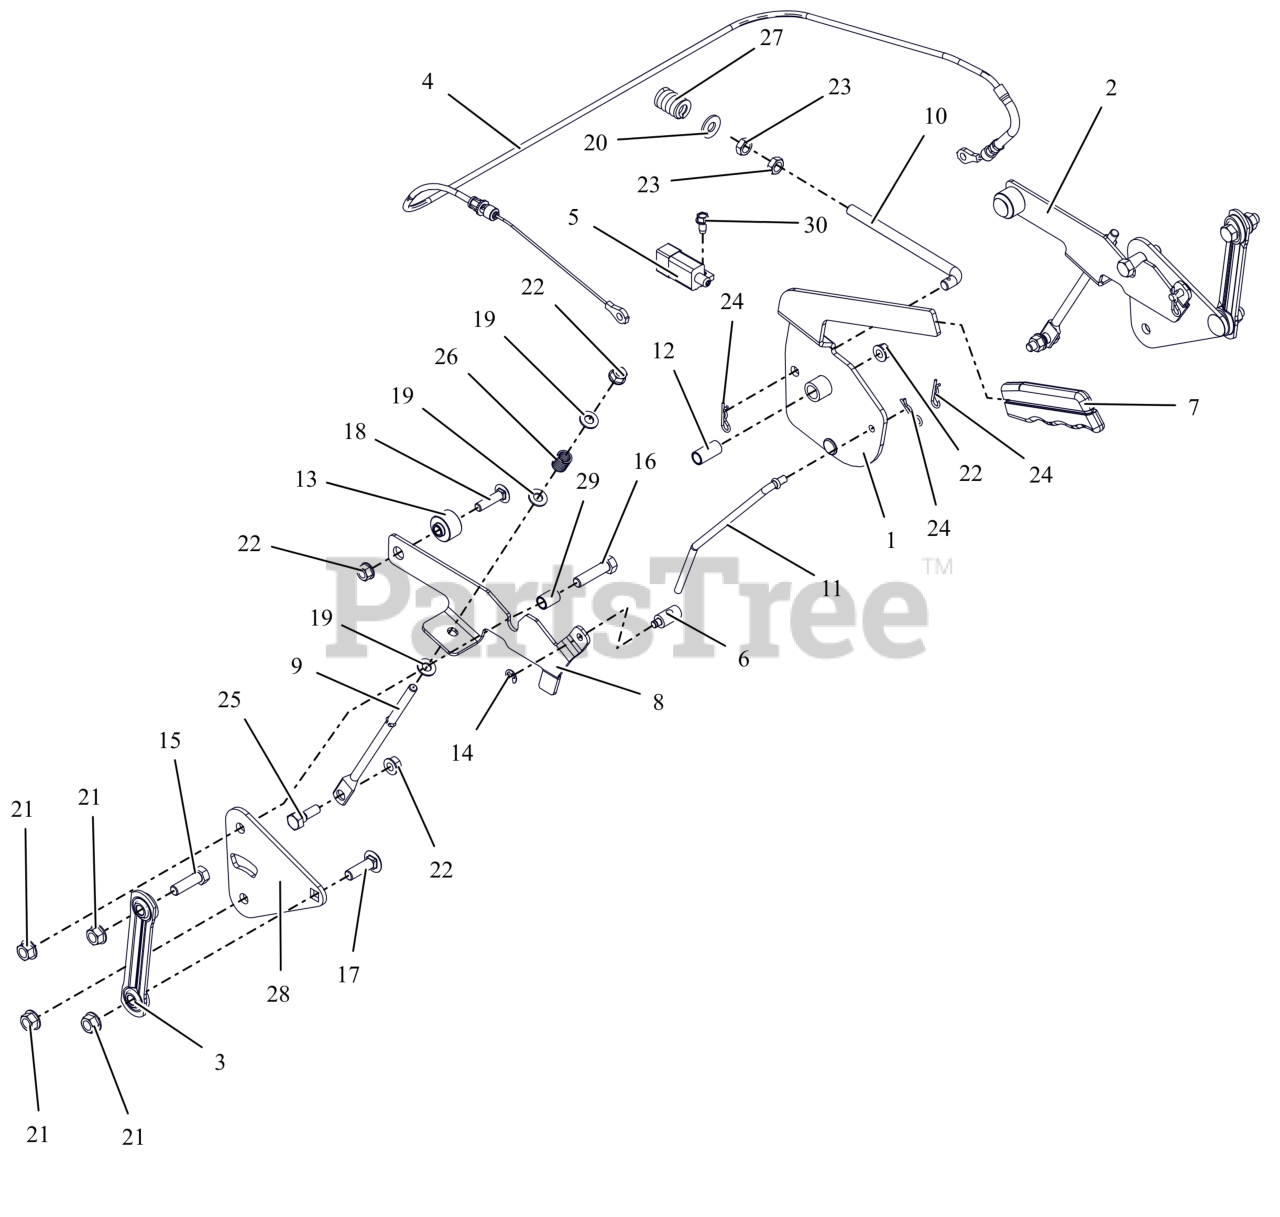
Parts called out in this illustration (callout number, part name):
1	LEVER, PARKING BRAKE
2	ARM, BRAKE - LH (W/PIN)
3	LINK, STAMPED STEERING
4	CABLE, BRAKE - PARKING
5	SWITCH-BRAKE NO/NO-POST & HOLE
6	TRUNION, 1/4-20
7	GRIP, PARKING (GRAY)
8	ARM, BRAKE - RH
9	ROD, LINK - TRANSMISSION BRAKE
10	ROD, OVER CENTER
11	ROD, BRAKE LINK
12	BSHG-SLV .385X.500X1.045
13	SPCR, FLANGE
14	RG-RTNG-EXT .250X.025
15	BLT, HEX .38-16X1.25 G5 ZCC
16	BLT, HEX .38-16X1.50 G5 ZCC
17	BLT,RHSSN .38-16X1.25 G5 ZCC
18	BTL,RHSSN .313-18 X 1.25 G5 ZCC
19	WSHR,FLT .344X.688X.065 ZCC
20	WSHR,FLT .375X.875X.083 ZCC
21	NUT-LK-TOP-FLG .38-16 ZC120
22	NUT-LK-TOP-FLG .312-18 GF ZCC
23	NUT-JAM .375-16 G2 ZCC
24	PIN, HAIR #213 .08X1.19 ZCC
25	BOLT,SHLDR .38X.25 -.31-18X.75
26	SPRING, COMPRESSION
27	SG-COMP .187X.56X1.62
28	PLATE, TRANSAXLE (BLACK)
29	SPCR SLEEVED .385X.500X.718
30	SCR-TAP .25-20X.50 HWH ZCC
